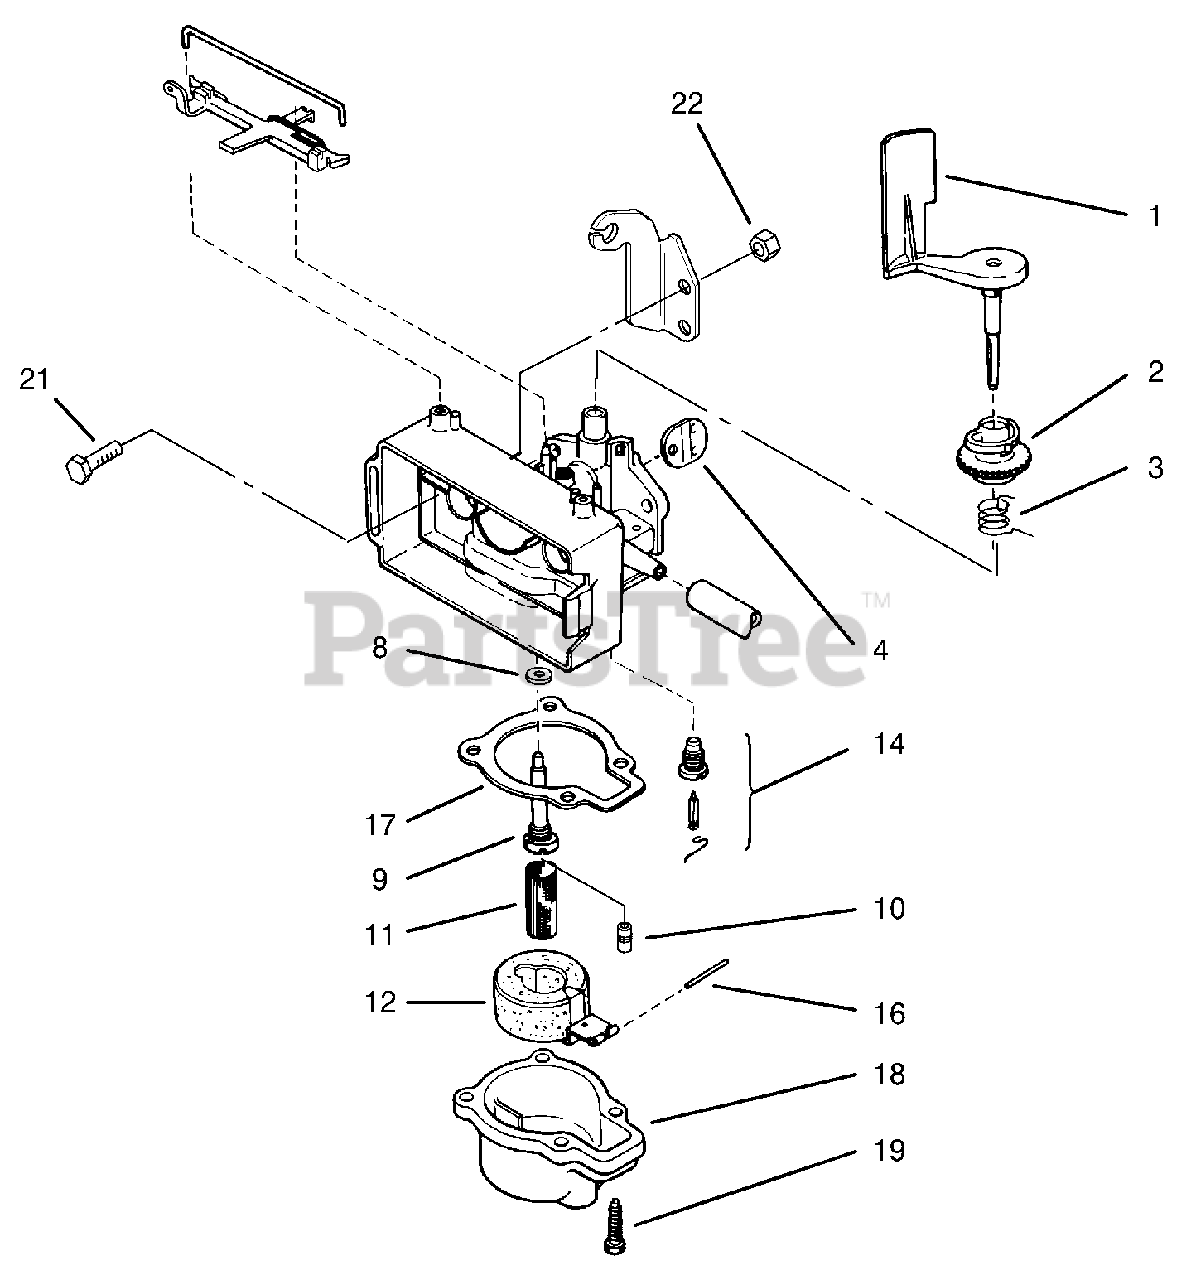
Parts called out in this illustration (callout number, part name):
1	Air Vane & Shaft
2	Collar-Adjust, Airvane
3	Spring-Throttle
4	Disc-Throttle
10	Main Jet
11	Filter-Fuel
12	Float & Arm ASM
14	Valve/Seat-Float
16	Pin-Straight
18	Chamber-Float
19	Screw-HH
22	Nut-Hex
